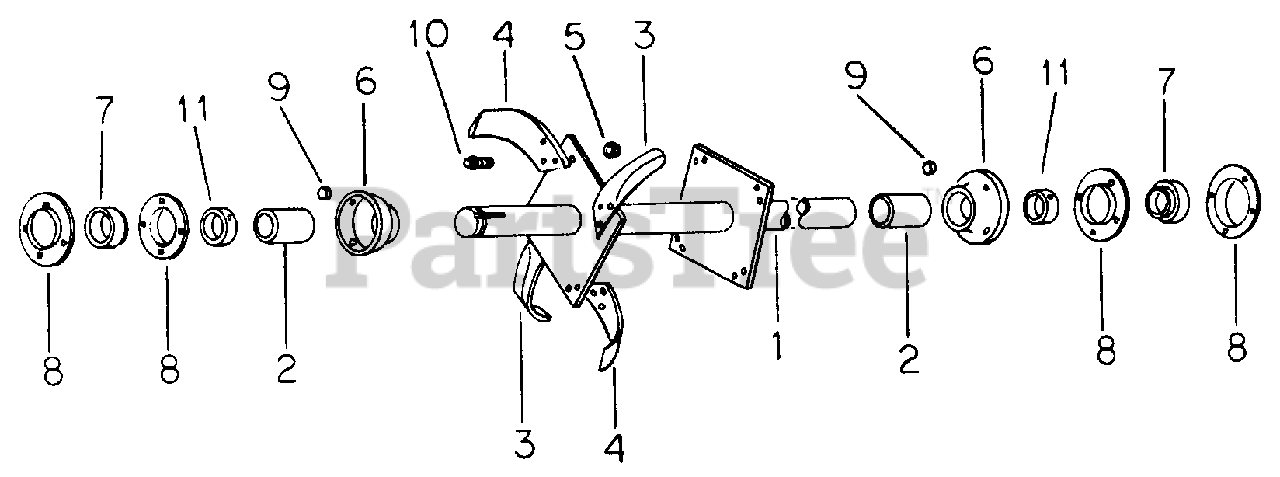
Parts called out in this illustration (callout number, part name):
1	SHAFT, ROTOR
2	SPACER, TINE SHAFT
5	NUT, SPECIAL
6	RETAINER, BRG GUARD
7	BEARING LESS COLLAR
9	WASHER
10	BOLT, 3/8 x 1-1/8 TYPE 8
11	COLLAR w/SET SCREW
